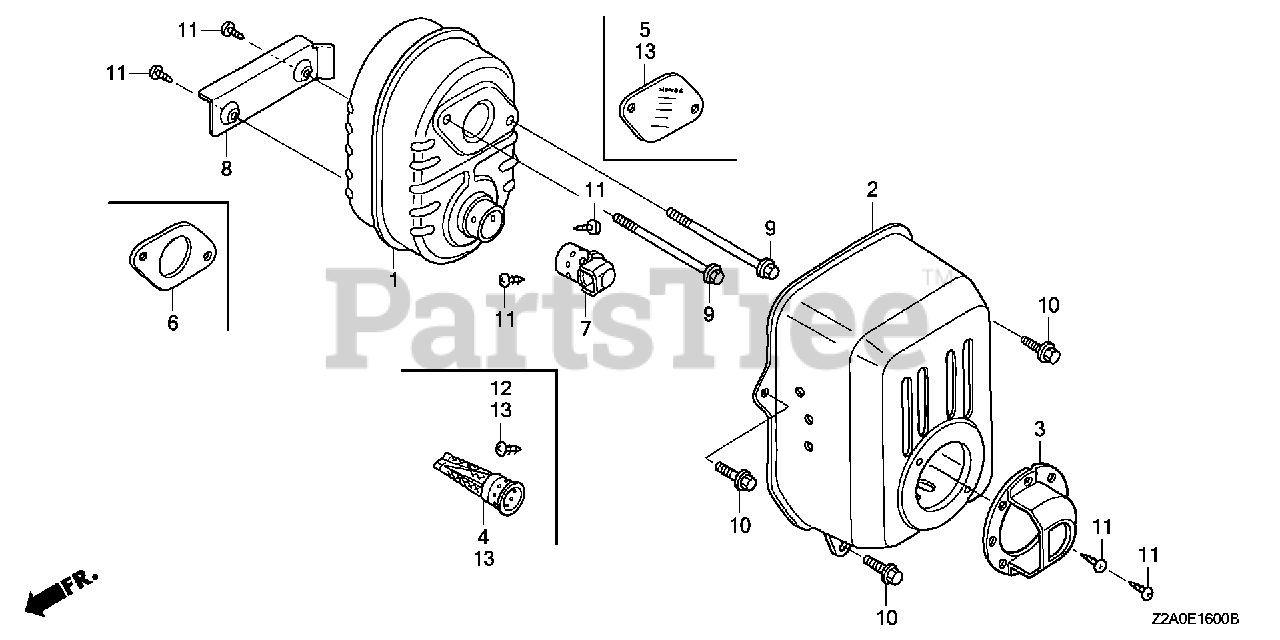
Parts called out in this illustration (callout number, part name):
1	MUFFLER
2	PROTECTOR, MUFFLER
4	ARRESTER, SPARK
5	PLATE, ARRESTER NUMBER
6	GASKET, MUFFLER
9	BOLT, FLANGE (6X79) (CT200)
10	BOLT, FLANGE (6X12) (CT200)
12	SCREW, TAPPING (4X6)
13	ARRESTER KIT, SPARK
